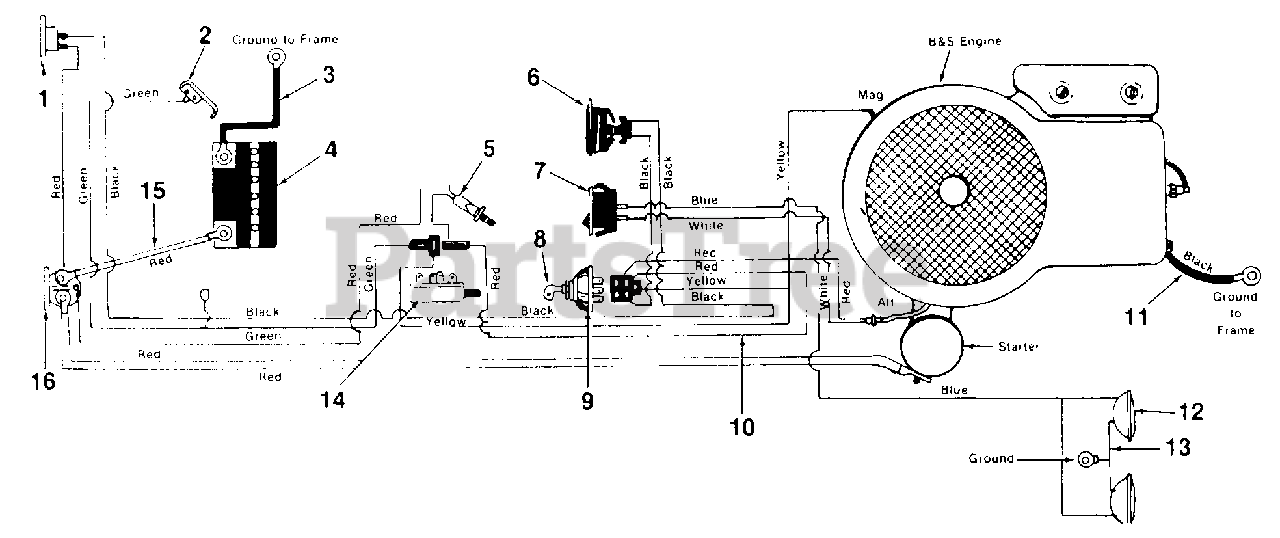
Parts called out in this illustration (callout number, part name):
1	Circuit Breaker
2	Spring Switch
3	Ground Wire 9.0" Lg.
4	12 Volt Battery
5	Safety Switch
6	Ammeter
7	Headlight Switch
8	Ignition Key
9	Ignition Switch
10	Wire Harness
11	Ground Wire 7.25" Lg. (Black)
12	Headlight
13	Ground Wire
14	Safety Switch
15	Electric Wire
16	Solenoid
